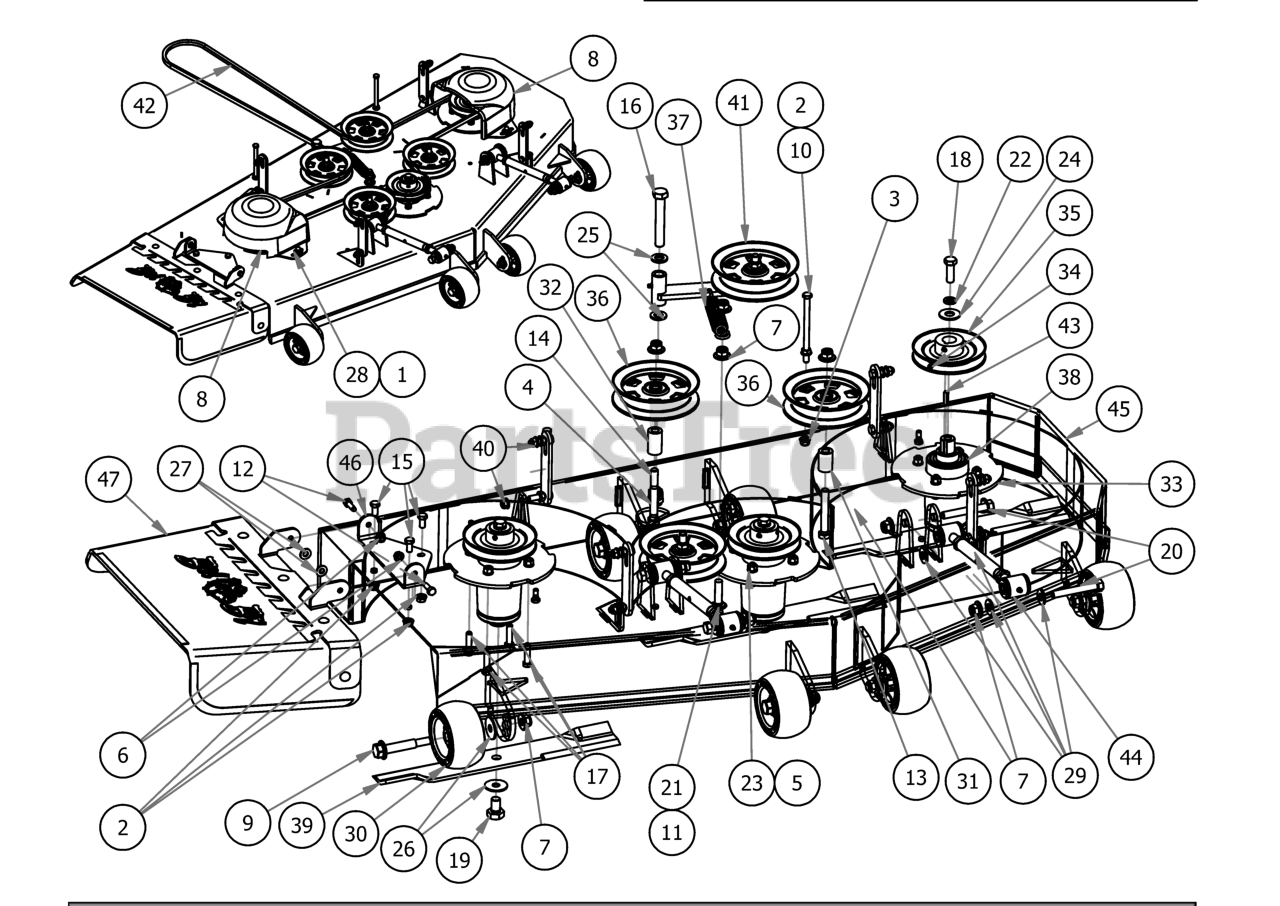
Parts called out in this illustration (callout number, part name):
1	Acorn nut-pulley Cover
2	3/8" Flange Nut
3	3/8" Nylock Flange Nut
4	5/8-11 Nylon Insert Jam Half Nut
5	3/8" Hex Nut
6	5/16" Nylon Flange Nut
7	1/2-13 Nylon Flange Nut
8	Pulley Cover
9	Deck Wheel Bolt
10	3/8-16 X 5-1/4 HEX CAP SCREW (GR.5) ZINC
11	1/2 x 2" Carriage Bolt
12	5/16-18 x 1 GR 5 Hex Bolt Zinc
13	1/2 x 3 1/2 Flange Bolt Grade 8
14	1/2" x 4" Bolt (Grade 8)
15	3/8" x 3/4" Hex Bolt
16	5/8" x 4" Hex Bolt
17	3/8 x 1.5" Bolt
18	1/2"-20 x 1 1/2 - Grade 5 Fine Thread Bolt
19	5/8" x 1 1/2" Grade 8 Hex Bolt (Fine)
20	1/2-13 x 3 1/2 GR 5 Hex Bolt
21	.517 Square Hole Round Washer
22	1/2" Lock Washer
23	3/8" Lock Washer
24	5/8'' Flat Washer
25	.630 ID Plastic Washer
26	1/2" Belleville Washer
27	.360 ID Plastic Washer
28	.360 ID Plastic Washer-Black
29	.505 Nylon Spacer
30	Deck Wheel
31	.502 ID X .750 OD X 1.500 Long Spacer
32	1 3/4" Pulley Spacer
33	Deck Spindle Support Plate
34	5/16 Set Screw
35	5.25" Deck Spindle Pulley
36	5-3/4 Idler Pulley
37	Deck Idler Spring
38	Spindle Assembly
39	54" Deck Fusion Blade For Outlaw
40	Deck Hanger Assembly
41	2017 54"/48" Deck Idler Assembly
42	B155.75 Deck Belt
43	1/4" x 1" Key
44	2018 Maverick Turnbuckle (Top Link)
45	54 ZT Welded Deck
46	Discharge Chute Hanger (deck mounted)
47	Discharge Chute Assembly
